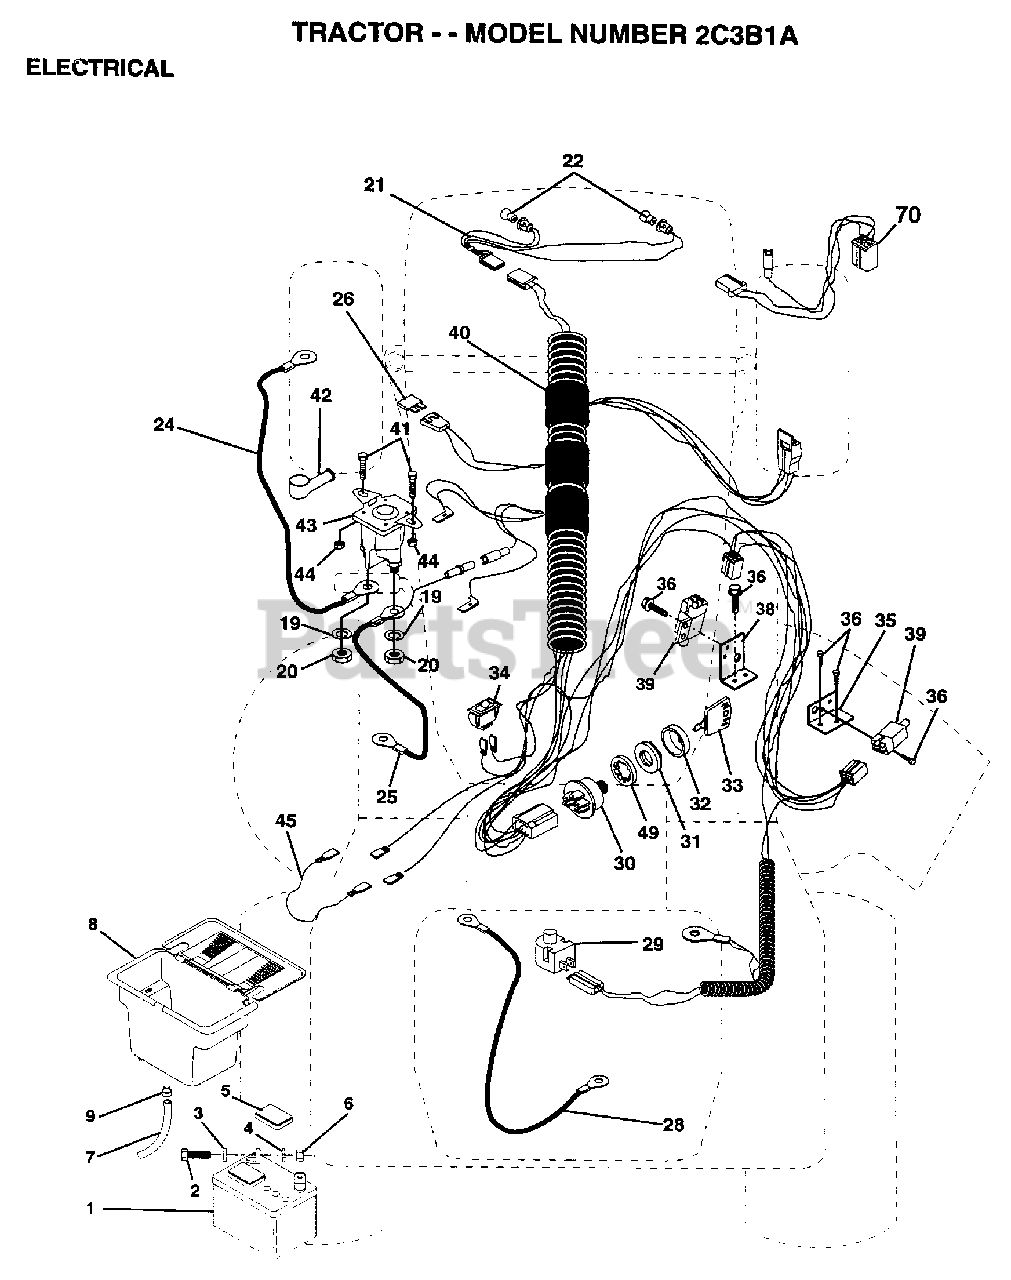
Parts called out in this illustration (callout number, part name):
2	BOLT LT
3	WASHER
4	LOCKWASHER
9	HOSE CLAMP T
20	NUT
21	"HARNESS,LIGHT SOC"
22	HEADLAMP BULB
24	CABLE T, BATTERY
25	CABLE.BTRY.6GA.RD
26	FUSE HYT
28	CABLE T
29	SWITCH SEAT *SUBS/2*
32	COVER KEY SWITCH
33	KEY STEEL DELTA
34	SWITCH LT
35	BRACKET LT
36	SCREW
38	BRACKET SWITCH IN
39	SWITCH INTERLOCKT (2 2)
40	HARNESS.IGN.DASH.
41	BOLT HXHD FIN
44	NUT HXKEP 1/4X20
45	ADAPTER AMMETER
49	LOCKWASHER
70	HARNESS ENG DUAL
